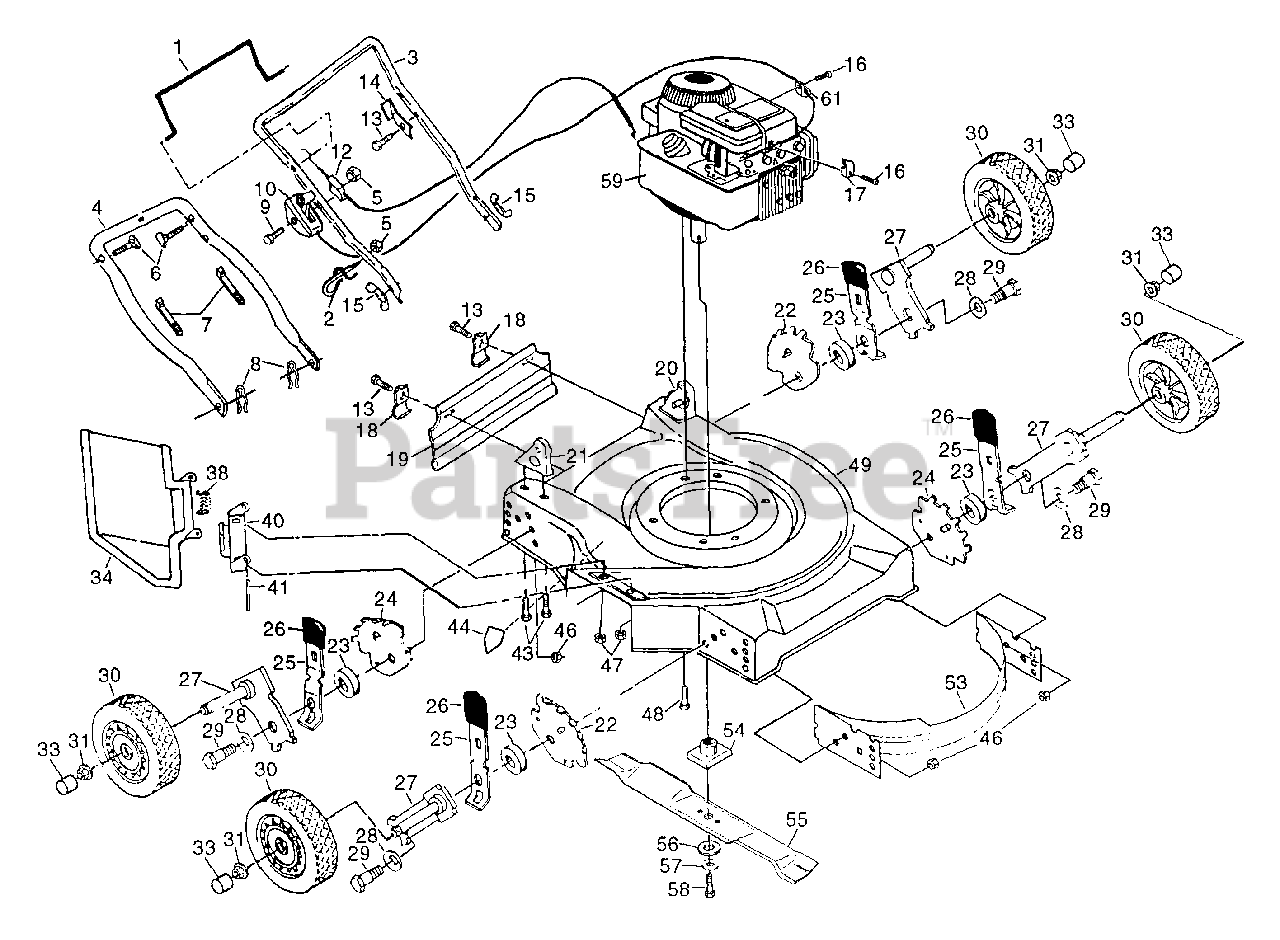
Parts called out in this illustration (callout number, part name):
1	Control Bar (AYP part number)
2	Rope Guide
3	Upper Handle (AYP part number)
4	Lower Handle (AYP part number)
5	Locknut (AYP part number)
6	Handle Bolt 5/16-18 x 1-3/4 (AYP part number)
7	Wire Tie (AYP part number)
8	Hairpin Cotter (AYP part number)
9	Hex Washer Head Screw 1/4-20 x 2.12 (AYP part number)
10	Throttle Control
12	Engine Zone Control Cable
13	Hex Washer Head Screw #10-24 x 1/2 (AYP part number)
14	Up-Stop Bracket (AYP part number)
15	Wing Nut (AYP part number)
16	Screw #10 x 5/8 (AYP part number)
17	Cable Clamp (AYP part number)
18	Skirt Bracket (AYP part number)
19	Rear Deflector (AYP part number)
20	Handle Bracket Assembly (Left)
21	Handle Bracket Assembly (Right) (AYP part number)
22	Wheel Adjusting Bracket LR/RF
23	Height Adjuster Spacer (AYP part number)
24	Wheel Adjusting Bracket RR/LF
25	Selector Spring (AYP part number)
26	Selector Knob (AYP part number)
27	Axle Arm (AYP part number)
28	Belleville Washer (AYP part number)
29	Shoulder Bolt 3/8-16 x 1 (AYP part number)
30	Wheel Assembly (AYP part number)
31	Flanged Locknut (AYP part number)
33	Hubcap (AYP part number)
34	Discharge Guard
38	Torsion Spring (AYP part number)
40	Deflector Hinge (AYP part number)
41	Hinge Rod (AYP part number)
42	Flat Washer (AYP part number)
43	Screw 5/16-18 x 3/4 (AYP part number)
44	Danger Decal (AYP part number)
46	Locknut 3/8-16 (AYP part number)
47	Hex Nut (AYP part number)
48	Hex Head Thread Rolling Screw 3/8-16 x 1 (AYP part number)
49	Mower Housing
53	Front Baffle (AYP part number)
54	Blade Adapter (AYP part number)
55	Blade 20" (AYP part number)
56	Hardened Washer (AYP part number)
57	Helical Lockwasher 3/8 (AYP part number)
58	Hex Head Screw 3/8-24 x 1-3/8 (Grd. 8)
61	Guide Clip (AYP part number)
